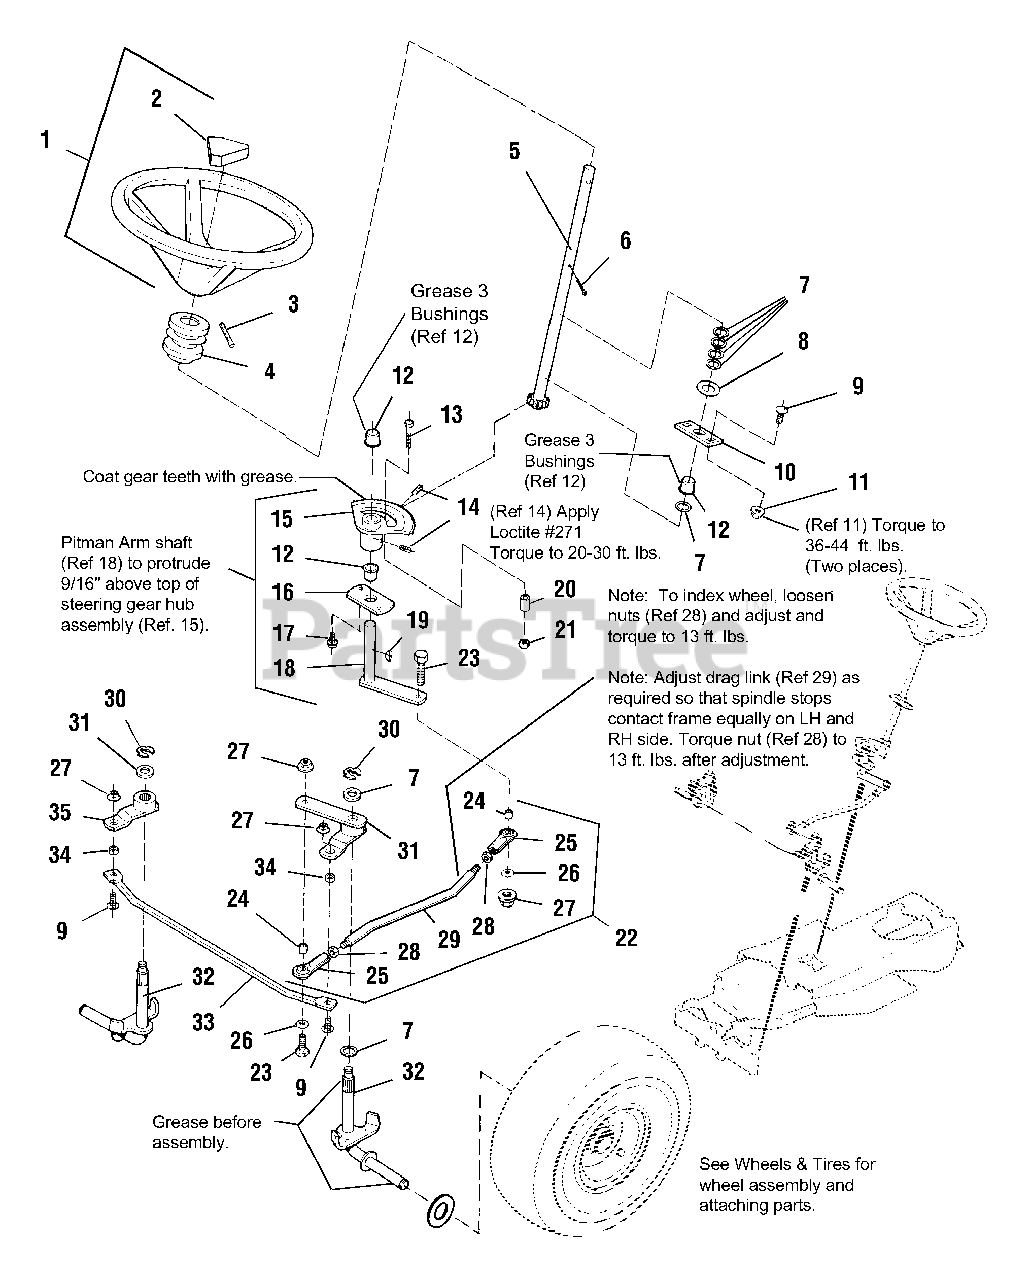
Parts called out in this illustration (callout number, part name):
1	STEERING WHEEL, 15"
2	CAP, Steering Wheel
3	PIN, Spring, 5/16 x 2-1/2
4	TUBE, Steering
5	SHAFT ASSY., Steering
7	WASHER, Plain, 49/64
8	WASHER, Plain
9	CAPSCREW, Hex Head, 3/8-16 x 1.38
10	PLATE, Mounting, Steering
11	NUT
12	BUSHING, Nylon
13	CAPSCREW, Hex Hd., 5/16-18 x 1-1/2
14	SETSCREW, Sq. Hd., 5/16-18 x 1/2
15	GEAR ASSY., Steering
16	SECTOR MOUNTING PLATE
17	SCREW, Taptite, 5/16-18 x 3/4
18	PITMAN ARM ASSY.
19	KEY, Hi Pro
20	SPACER, Stop
21	NUT, Hex, Lock ESNA Light, 5/16-18
22	DRAG LINK ASSY.
23	CAPSCREW, Hex Hd., 3/8-16 x 1-3/8
26	WASHER
27	NUT, Hex, Lock, Flange, 3/8-16
28	NUT, Hex, Jam, 1/2-20
31	ARM ASSY., Steering, LH
32	SPINDLE ASSY.
35	ARM ASSY., Steering, RH
